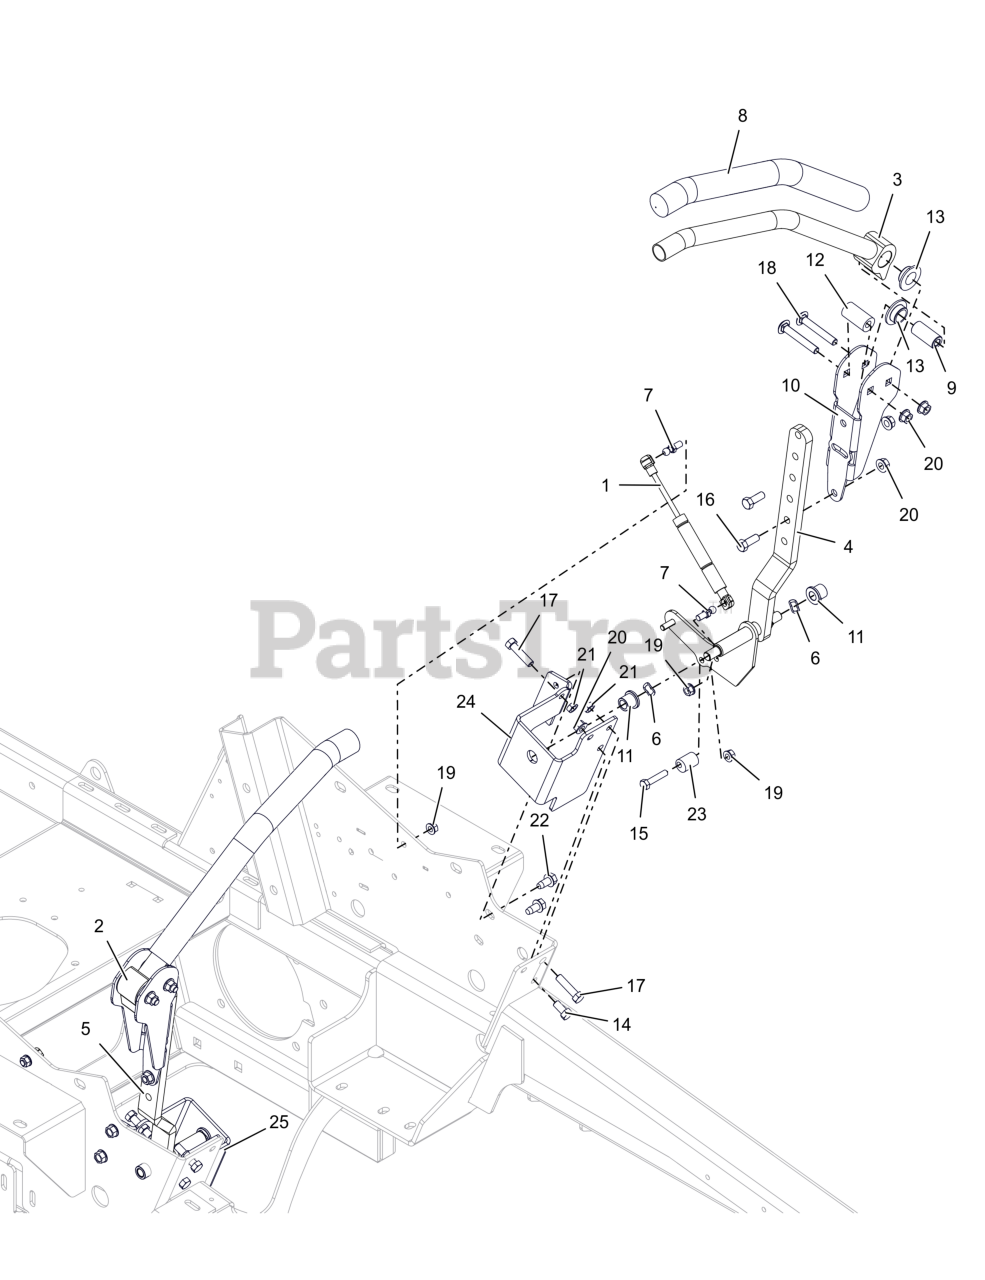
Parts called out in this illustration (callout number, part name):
1	DAMPER, CONTROL
2	WLDMT, CONTROL HANDLE (RED)
3	WLDMT, CONTROL HANDLE (RED)
4	WLDMT, LH LOWER CONTROL ARM (RED)
5	WLDMT, RH LOWER CONTROL ARM (RED)
6	WAVE WASHER .531X.781X.125FH
7	STUD- BALL
8	GRIP, HANDLEBAR
9	SPACER, STEERING ARM
10	BRKT, ADJ UPPER CONTROL ARM (RED)
11	BHSG-FLG .500X.750X.750X.125
12	BSHG, ECCENTRIC.406X.875X1.625
13	BSHG, FLANGED .762 X 1.48 X .44 IGLIDER
14	BLT,HEX .38-16X.75 G5 ZCC
15	BLT, HEX .31-18X1.50 G5 ZCC
16	BLT,HEX .38-16X1.00 G5 ZCC
17	BLT, HEX 0.375-16X1.5FULL G5 ZCC
18	BLT, RHSSN.38-16X2.50 G5 ZCC
19	NUT,LK-CTR-FLG .31-18 GF ZCC
20	NUT-LK-CTR-FLG .375-16 GF ZCC
21	NUT-JAM .375-16 G2 ZCC
22	SCR,TAP .375-16X.75 HWH TR ZCC
23	ECCENTRIC
24	BRKT, CONTROL ARM - LEFT (RED)
25	BRKT, CONTROL ARM - RIGHT (RED)
